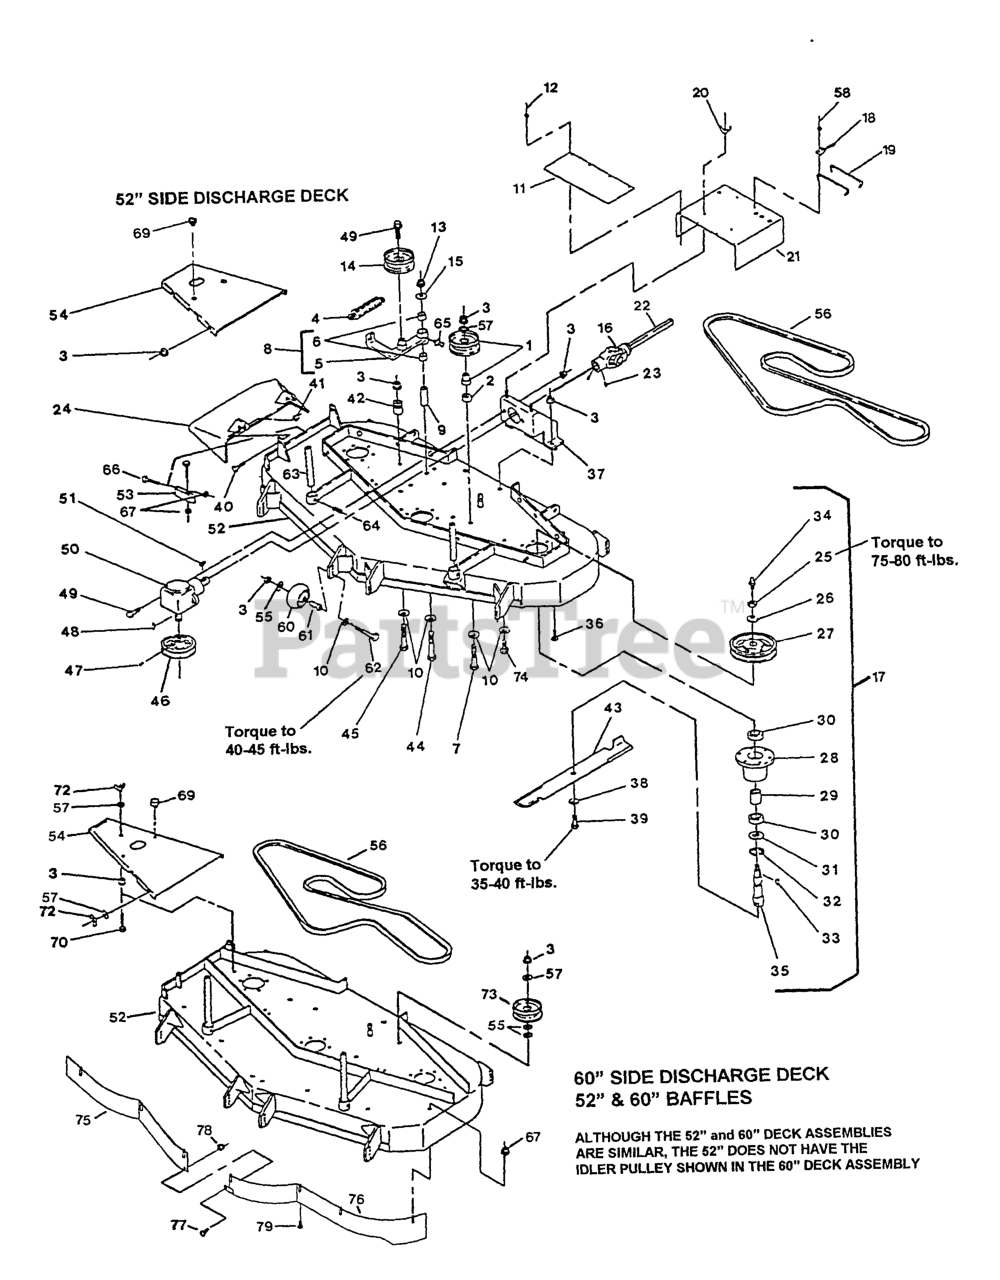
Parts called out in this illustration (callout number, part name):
1	KIT,48 RH IDLER/BUS
4	SPRING,EXTENSION
6	SLEEVE-BEARING
9	BUSHING
11	SHIELD,PTO GUARD
12	RIVET-POP
14	IDLER,PULLEY
17	CH-52&60 OUTER CUTTR
18	CLIP-DECK, HOLD UP ROD
20	WINGNUT-NYLOCK
22	PTO SHAFT,SHAFT HALF PNT
24	WLD,CHUTE DISCHARGE
26	WASHER-SPRING
27	SHEAVE,BLADE DRIVE
29	SPACER,BEARING
30	BEARING,HD SPINDLE
31	SEAL,MECHANICAL DUST
32	RING,SNAP WLDS N5000-244
35	SPINDLE-OUTER BLADE
36	SCRW,TPTTE HH
37	WLD,GEARBOX SUPPORT
38	WASHER-SPRING
42	ANCHOR-SPRING PLTD
47	SCREW-SET
50	GEARBOX, PEERLESS
53	WLD,BAFFLE DISCHARGE
58	Rivet, 3/16
60	ROLLER-SCALP, ANTI
61	BUSHING-ROLLER
63	ROD,DECK SUPPORT
72	NUT-WING
73	IDLER,PULLEY
77	BOLT-CARR
